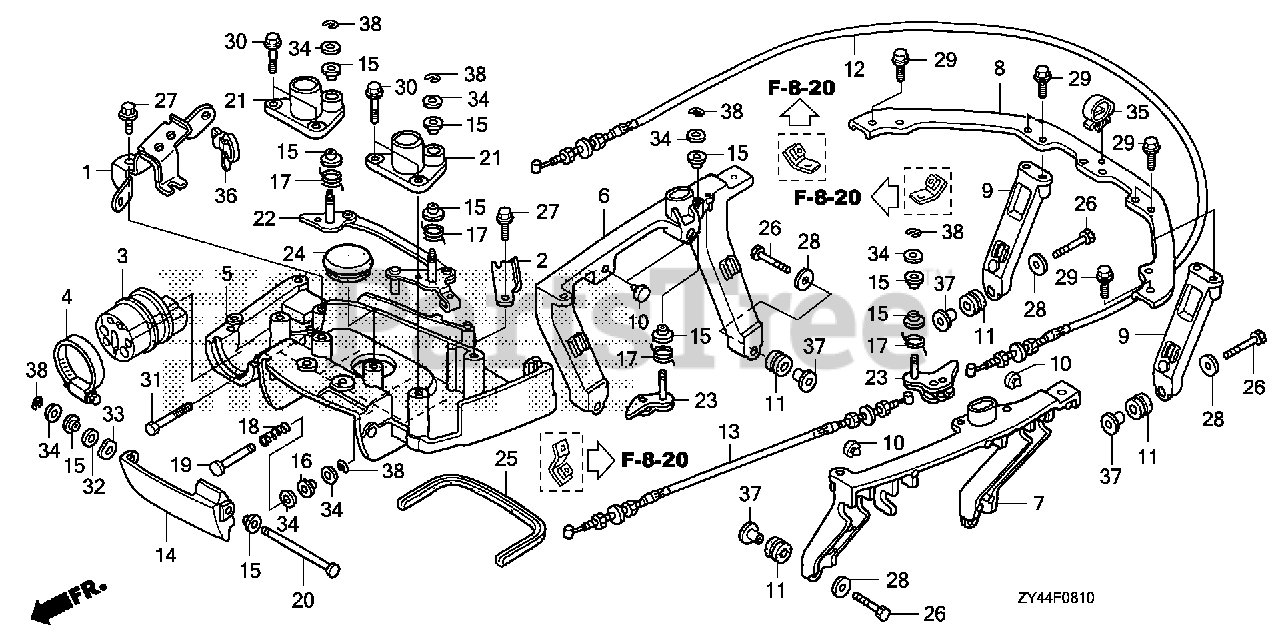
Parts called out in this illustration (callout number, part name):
1	BRACKET, CABLE
2	PLATE, STARTER CABLE
3	GROMMET A, CASE (LOWER)
4	BAND, CASE GROMMET (LOWER)
5	BRACKET, FR. COVER *NH8* (DARK GRAY)
6	BRACKET, R. SIDE COVER
7	BRACKET, L. SIDE COVER
8	BRACKET A, RR. COVER
9	BRACKET B, RR. COVER
10	RUBBER, STOPPER
11	RUBBER, FR. CARRIER CUSHION
12	CABLE A, COVER LOCK
13	CABLE B, COVER LOCK
14	LEVER, COVER LOCK *NH282MU* (OYSTER SILVER METALLIC-U)
15	BUSH A, COVER LOCK
16	BUSH B, COVER LOCK
17	SPRING, COVER LOCK HOOK
18	SPRING, LOCK LEVER RETURN
19	SHAFT, COVER OPEN
20	SHAFT, FR. LOCK
21	HOLDER, STRIKER
22	LOCK ASSY., FR.
23	LOCK, SIDE
24	CAP, L. SIDE COVER
25	SEAL D, COVER (LOWER)
26	BOLT, HEX. (8X35)
27	BOLT, FLANGE (6X14)
28	WASHER, PLAIN (8MM)
29	BOLT, FLANGE (6X12)
30	BOLT, FLANGE (6X20)
31	BOLT, FLANGE (8X22)
32	WASHER, PLAIN (10MM)
33	WASHER, WAVE (10MM)
34	WASHER, PLAIN (8MM)
35	CLIP, HARNESS
36	CLIP, HARNESS BAND (145MM) (BLACK)
37	COLLAR (8.5X14.5)
38	E-RING (6MM)
